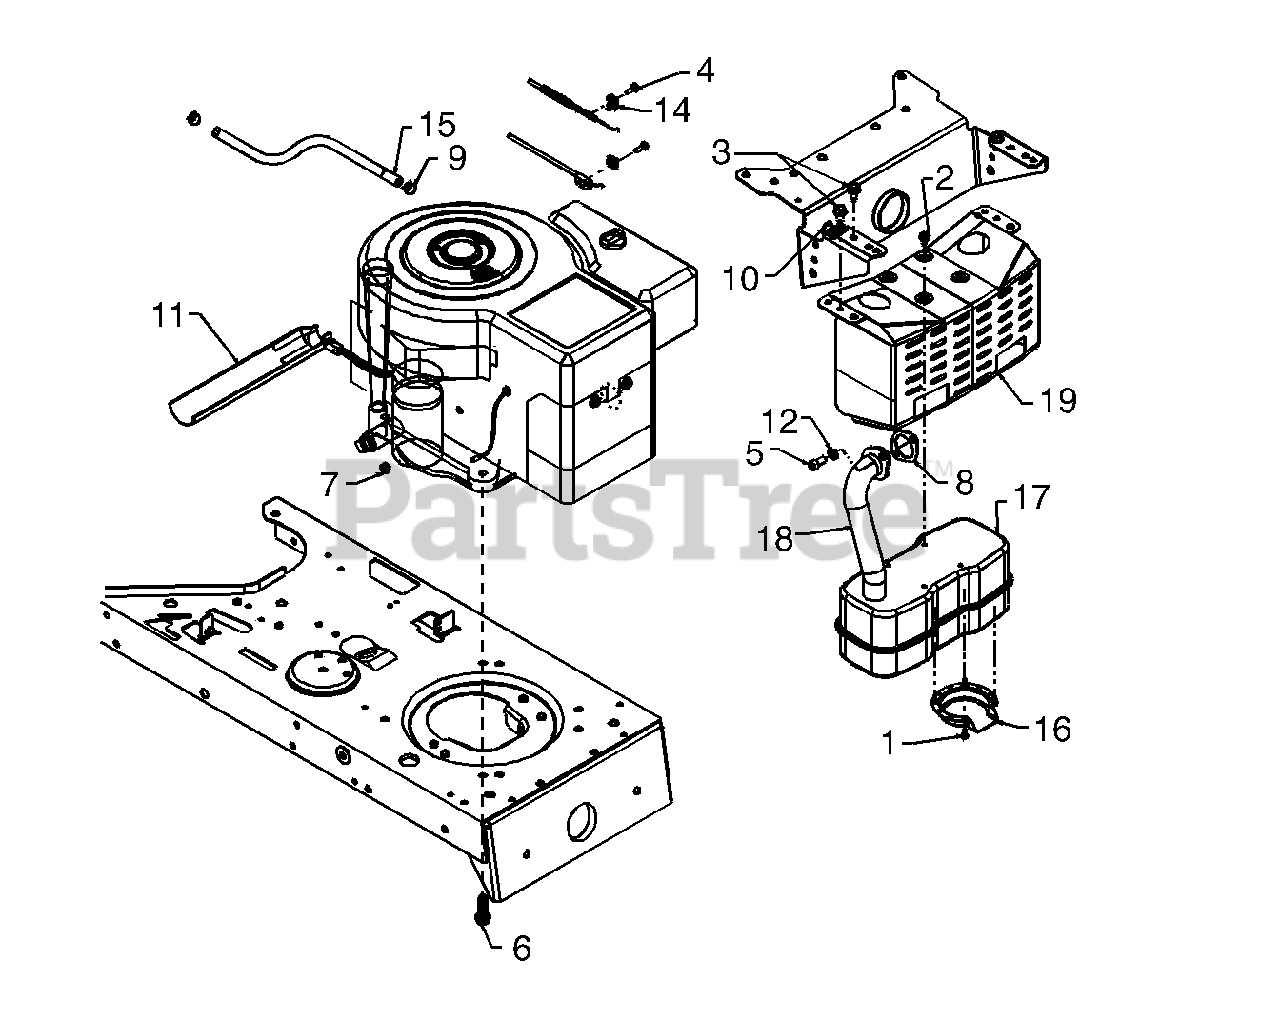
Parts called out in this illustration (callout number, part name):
1	Hex Tap Scr. #8-32 x .38" Lg.
2	Hex TT-Tap Scr. 1/4-20 x .5" Lg.
3	Hex TT-Tap Scr. 5/16-18 x .62"
4	Hex Wash. Scr. #10-32 x .62"
5	Socket Head Scr. 5/16-18 x .62"
6	Hex TT-Tap Scr. 3/8-16 x 1.25"
7	Hex Sems Scr. 1/4-20 Thd.
8	Gasket
9	Hose Clamp
10	Clamp
11	Oil Drain Sleeve
12	Lock Washer 5/16" I.D.
14	Casing Clamp
15	Fuel Line 12" Lg.
16	Muffler Deflector
17	Muffler
18	Exhaust Pipe
